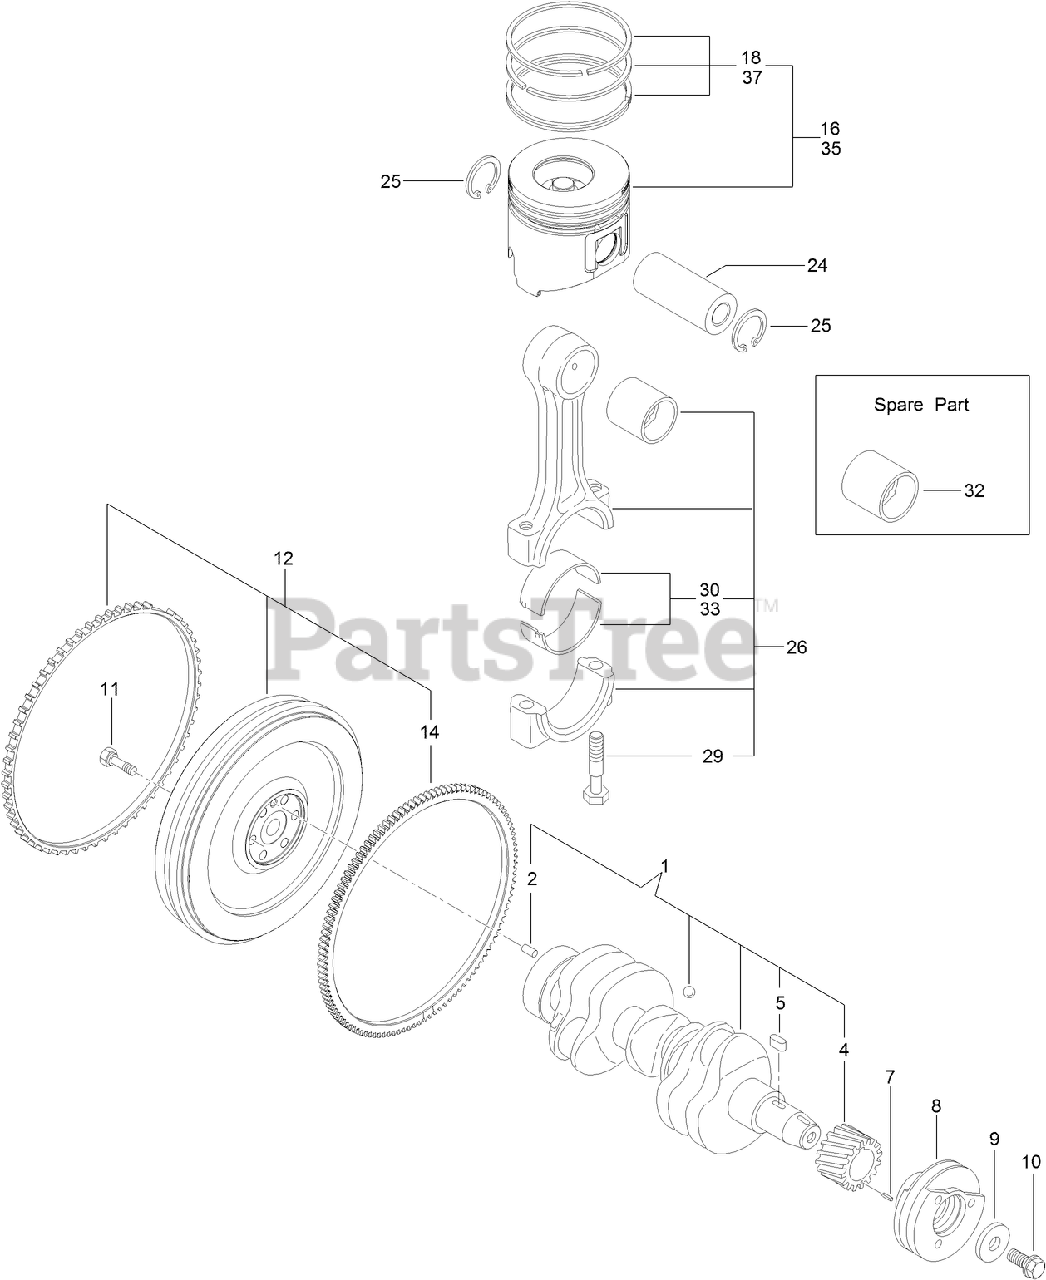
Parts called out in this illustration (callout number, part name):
1	CRANKSHAFT ASM
7	PIN-SPRING
8	PULLEY-V
9	WASHER
12	FLYWHEEL ASM
16	PISTON ASM
18	PISTON RING ASM
26	CONNECTING ROD ASM
30	PIN-CRANK
32	PIN-PISTON
33	PIN-CRANK (.25)
35	PISTON ASM (0.25 O S)
37	RING SET (0.25 O S)
